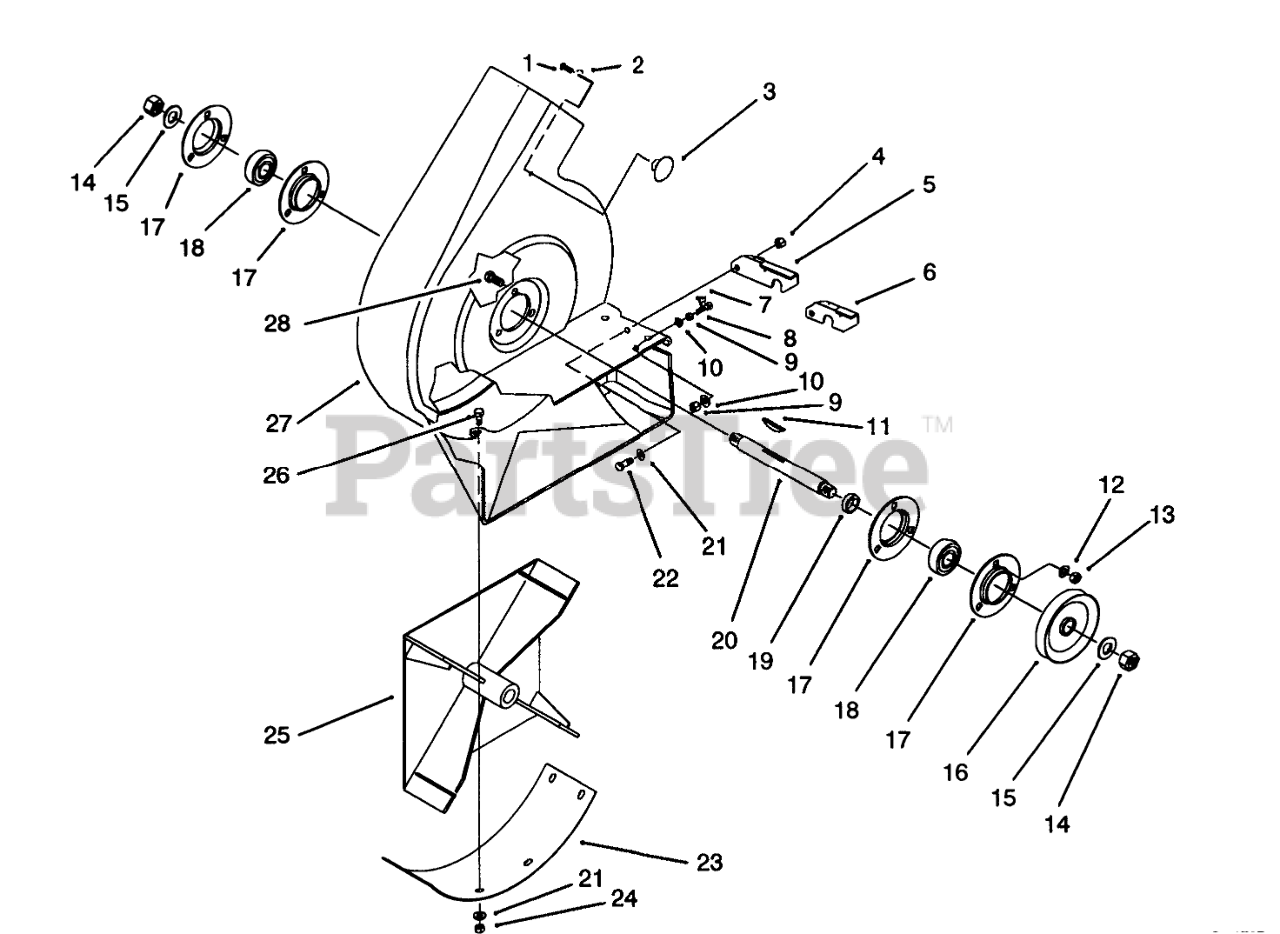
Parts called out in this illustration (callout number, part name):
1	SCREW-PPHTF
2	WASHER-PLAIN
4	NUT-LOCK, NI
5	48" BLOWER LATCH B
6	42" BLOWER LATCH B
7	SPRING-EXTENSION
8	SCREW-HWH
9	NUT-HEX
10	WASHER-FLAT
12	WASHER-LOCK
13	NUT-HEX
14	NUT-JAM
15	WASHER-LOCK
16	PULLEY-BLOWER
17	FLANGE
18	BEARING-BALL
19	Spacer
20	SHAFT-BLOWER
21	WASHER-FLAT
22	SCREW-HH
23	COVER-BLOWER, BOTTOM
24	NUT-LOCK, NI
25	Impeller
26	SCREW-CARRIAGE
27	HOUSING-VAC, BLOWER
28	BOLT-CARR
